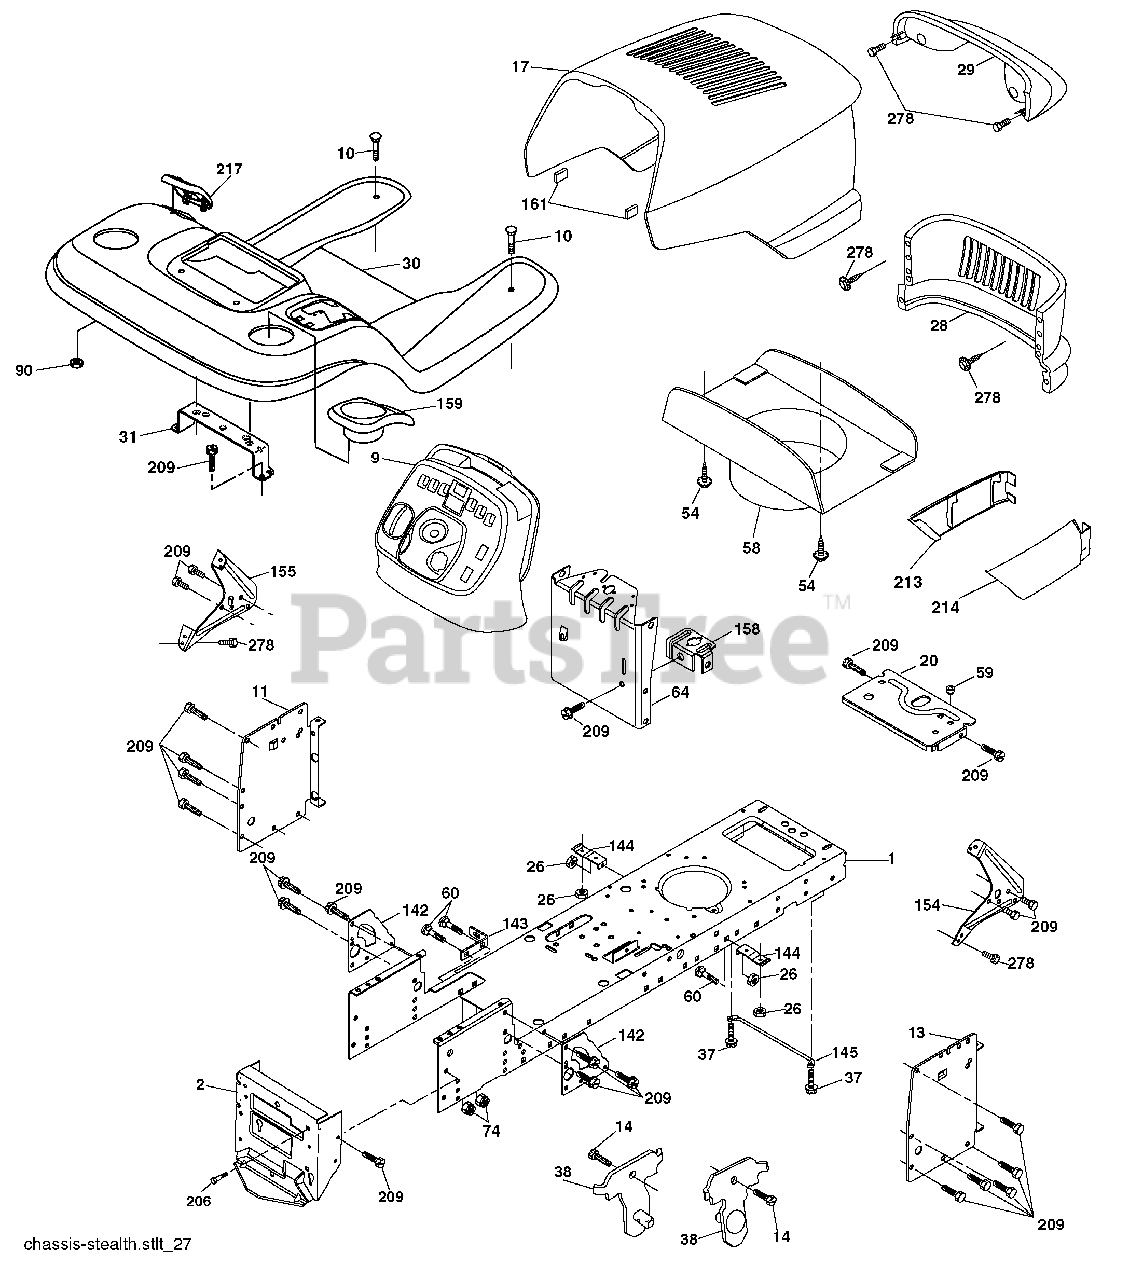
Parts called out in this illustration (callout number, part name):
1	Chassis
2	Drawbar
9	Dash
10	Bolt Carriage 3/8-16 x 1
11	Panel Dash Lh
13	Panel Dash Rh
14	Screw Thdrol 3/8-16 x 1/2
17	Hood
20	Plate Battery
26	Nut Lock Hex W/Ins 3/8-16 unc
28	Grille
29	Lens Bar
30	Fender Footrest
31	Bracket Fender
37	Screw Thdrol 6/16-18 x 1/2 TYT
38	Bracket Asm Pivot Mower Rear
54	Screw WSHD Hex 10-32 x 5/8
58	Duct Air
59	Bushing
60	Bolt RDHD Sqnk 3/8-16 unc x 3/4
64	Dash Lower STLT
74	Nut Crownlock 3/8-16 unc
90	Nut Self Thd Wsh - HD 1/4 Zinc
142	Plate Reinforcement STLT
143	Bracket Swaybar Chassis
144	Bracket Footrest Step-thru
145	Rod Pivot Chassis/Hood
154	Bracket Dash RH
155	Bracket Dash LH
158	Bracket Parking Brake
159	Cupholder
161	Bumper Hood
206	Bolt Shoulder 5/16-18
209	Screw Hexwsh Thdr 3/8-16 x 3/4
213	Skirt Grille LH
214	Skirt Grille RH
217	Console Fuel Window
278	Screw 10 x 3/4 Single Lead-Hex
